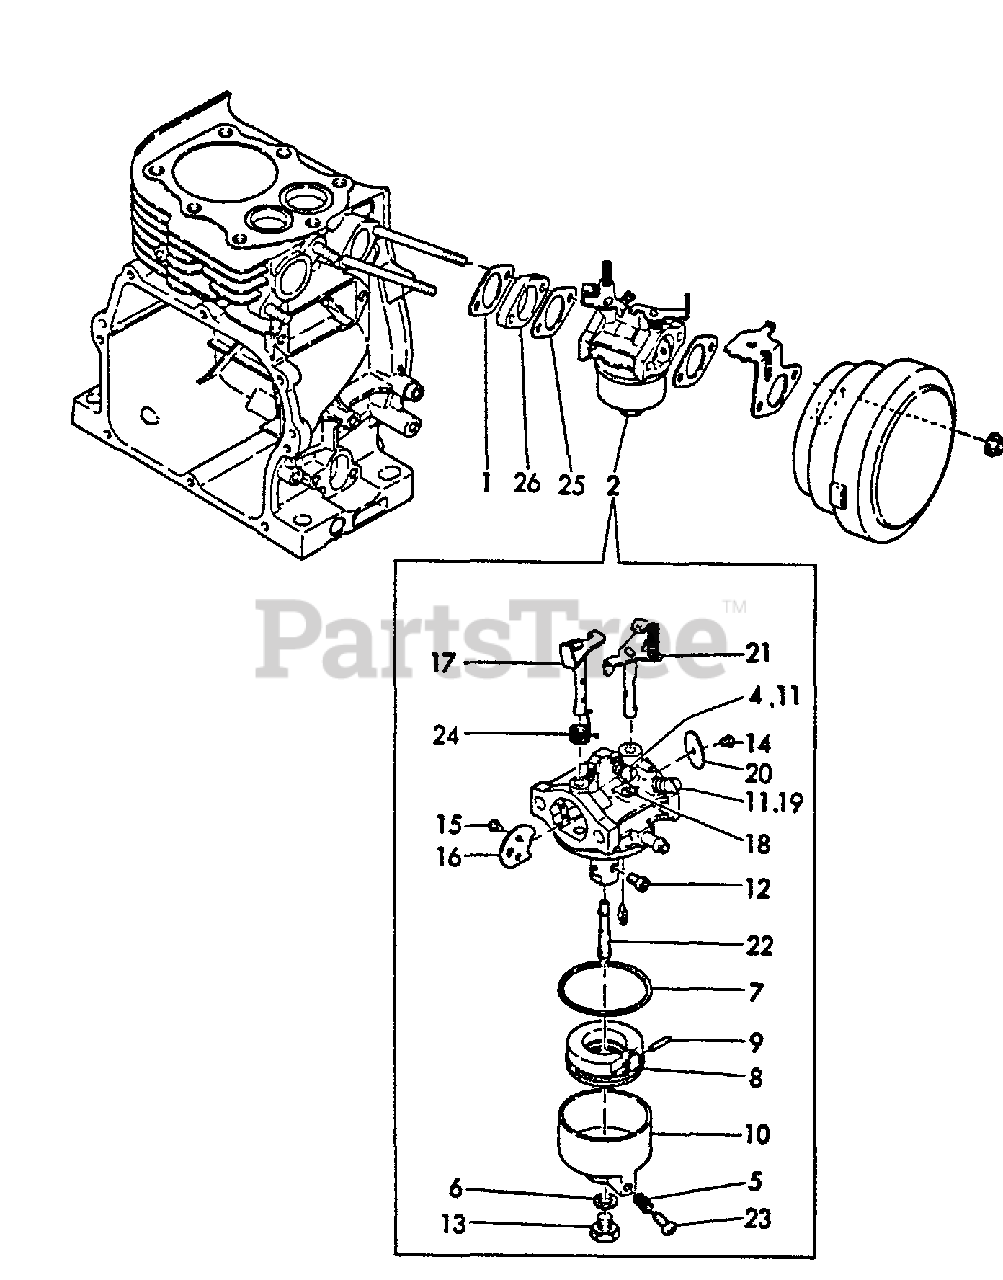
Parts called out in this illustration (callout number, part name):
1	GASKET, EXHAUST
2	CARBURETOR
4	SCREW
6	GASKET
7	GASKET
8	FLOAT
9	PIN
10	BODY, FLOAT CHAMBER
11	SPRING
12	JET, MAIN
14	SCREW
16	VALVE
17	SHAFT, CHOKE
18	JET, PILOT
19	SCREW
20	VALVE, THROTTLE
21	SHAFT ASSY, THROTTLE
22	NOZZLE, MAIN
23	SCREW
24	SPRING
25	GASKET, INTAKE
26	SPACER
